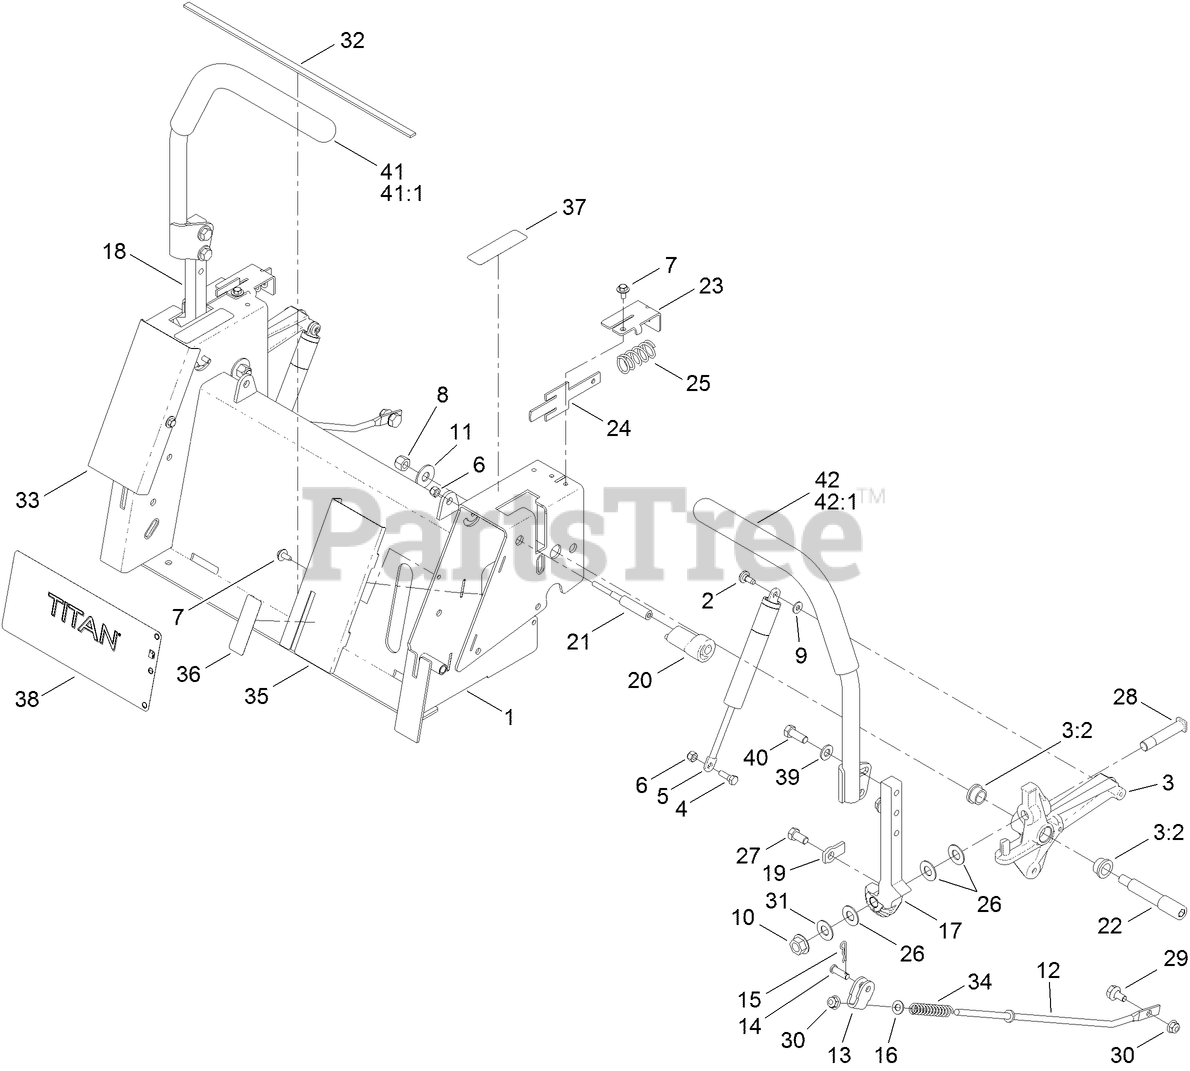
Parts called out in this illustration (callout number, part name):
1	BOX-CONTROL
2	SCREW-SHOULDER
3	ACTIVATOR ARM ASM
3:2	BUSHING
4	BOLT-SHOULDER
5	DAMPER-CONTROL, MOTION
6	NUT-LOCK, NI
7	SCREW-HHFTF
8	NUT-LOCK, NI
9	WASHER
10	NUT-HF
11	WASHER-FLAT
12	ROD-CONTROL
13	BRACKET-CONTROL
14	PIN-CLEVIS
15	PIN-COTTER
16	WASHER-PLAIN
17	ARM-ACTUATOR, LH
18	ARM-ACTUATOR, RH
19	TAB-STOP
20	ECCENTRIC
21	SCREW-ECCENTRIC
22	BOLT-SHOULDER
23	BRACKET-RETURN
24	PLATE-RETURN
25	SPRING-COMPRESSION
26	WASHER-PIVOT
27	SCREW-HH
28	BOLT-SHOULDER
29	BOLT-SHOULDER
30	NUT-HF, NI
31	WASHER-TEFLON
32	STRIP-VIBRATION, ANTI
33	COVER-CONTROL, RH
34	SPRING-RETURN, NEUTRAL
35	COVER-CONTROL, LH
36	DECAL-BRAKE, PARKING
37	DECAL-CONTROL, MOTION
39	WASHER-FLAT
40	SCREW-HH
41	HANDLE-CONTROL, RH
42	HANDLE-CONTROL, LH
